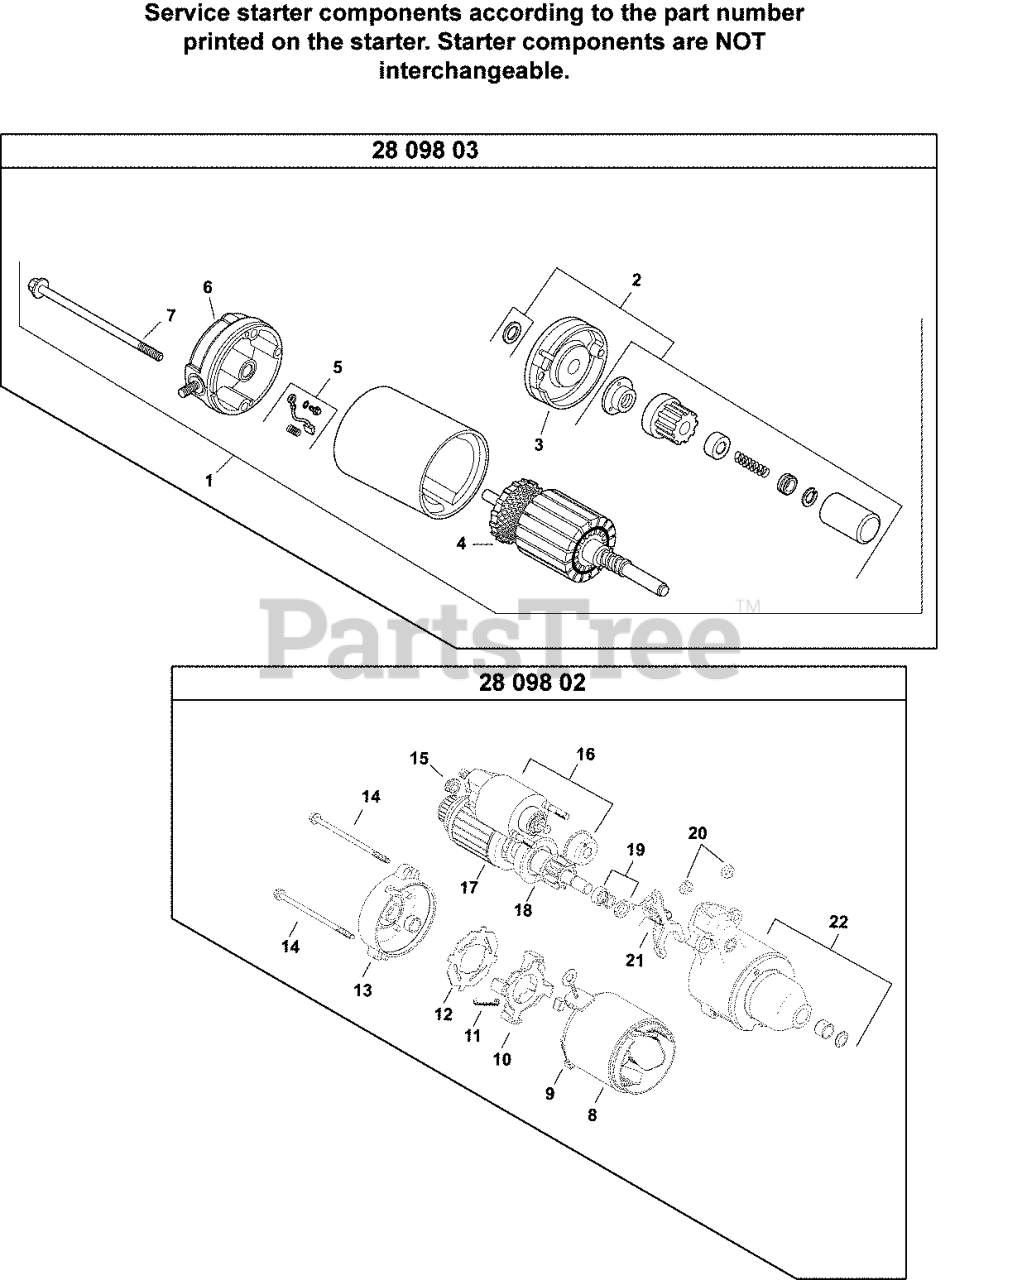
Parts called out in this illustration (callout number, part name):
1	KIT, STARTER - (#DSC)
2	KIT, DRIVE
3	CAP, DRIVE
4	ARMATURE ASSY - DISCONTINUED
5	KIT, BRUSH & SPRING - DISCONTINUED
6	CAP, COMMUTATOR (#DSC)
7	THRU BOLT
8	FRAME W/BRUSHES - DISCONTINUED
9	BRUSH & SPRING KIT
10	BRUSH HOLDER
11	SPRING, BRUSH
12	INSULATOR
13	CAP, COMMUTATOR END
14	THRU BOLT
17	ARMATURE-DISCONTINUED
18	CLUTCH ASSEMBLY-DISCONTINUED
19	KIT, STARTER REPAIR
21	LEVER, STARTER DRIVE
22	HOUSING ASSEMBLY - DISC.
